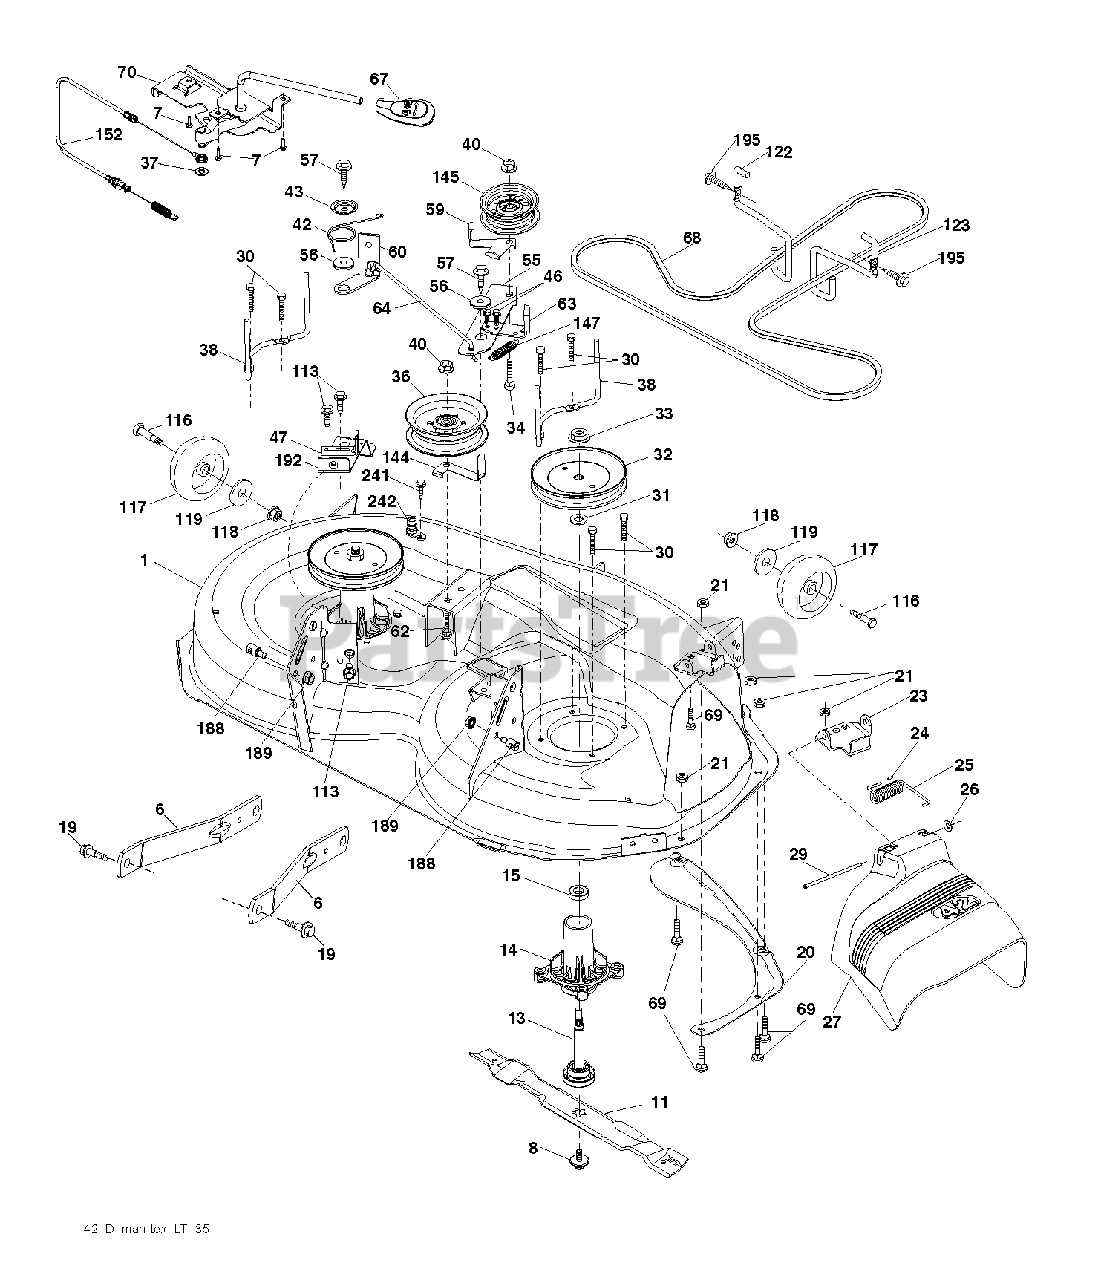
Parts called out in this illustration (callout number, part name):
1	DECK.WELDMNT.42"GREYMS498
6	ARM.SUSPENSION.MOWER.R
7	SCREW.#10 X 0.750.BOS
8	BOLT.WASHER.ASM.7/16-2
11	42" HI-LIFT BLADE
13	SHAFT.ASM.MDRL.N/GREASE.38
14	HOUSING.MANDREL.4PT.
19	BOLT.SHOULDER
20	BAFFLE.VORTEX
21	LOCKNUT
23	BRKT.DEFLECTOR.38"2005+
24	CAP-SLEEVE LT
25	SPRING.TORSION.DEFLECT
26	NUT PUSH M
27	SHIELD.DEFLECTOR.MOWER.42"BLAC
29	ROD.HINGE
30	SCREW, WASHER HEAD
31	WASHER.SPACER.MANDREL
32	PULLEY.MANDREL.5.438.PD
33	NUT.FLANGE.LOCK.TOP
34	BOLT.3/8-16X1.50
36	PULLEY.IDLER.2006
37	WASHER
38	KEEPER.BELT.MANDREL.PULLEY
40	NUT LOCK FLG 3/8-16 UNC
42	SPRING.TORSION.BRAKE
43	SRPING.TORSION.RETAINE
46	SCREW.1/4-20X5/8
47	BRKT.CLUTCH.CABLE
55	IDLER.ARM.42"
56	SPACER.RETAINER
57	SCREW 3/8-16X1
59	GUARD, BELT
60	ARM BRAKE MOWER
63	ARM BRAKE MOWER
64	LINKAGE.BRAKE.ASM.ZINC
67	HANDLE.CLUTCH.CABLE.LT
68	BELT.DECK.DRIVE.42"
69	BOLT
70	CLUTCH.ASM.MANUAL.LT.PRED
113	BOLT.5/16HEX.WHS.HD
116	BOLT M
117	WHEEL.GAGE.HALF.SPOKED
118	LOCKNUT
119	WASHER
122	KEEPER BELT ENGINE LH
123	KEEPER BELT RH
144	KEEPER.BELT.MOWER
145	PULLEY.IDLER.48"PRIMARY
147	RETURN SPRING
152	CABLE.CLUTCH.MANUAL.
188	STUD.FASTNER.W/ANTI-ROTATE
189	NUT LOCK HEX FLANGE 5/16-18
192	BRKT.BRAKE.STAND.LH.
195	SCREW, 3/8-16X3/4
241	SCREW.TT.#10-32X.5.3/8.FLANGE
242	PORT.WASHOUT
